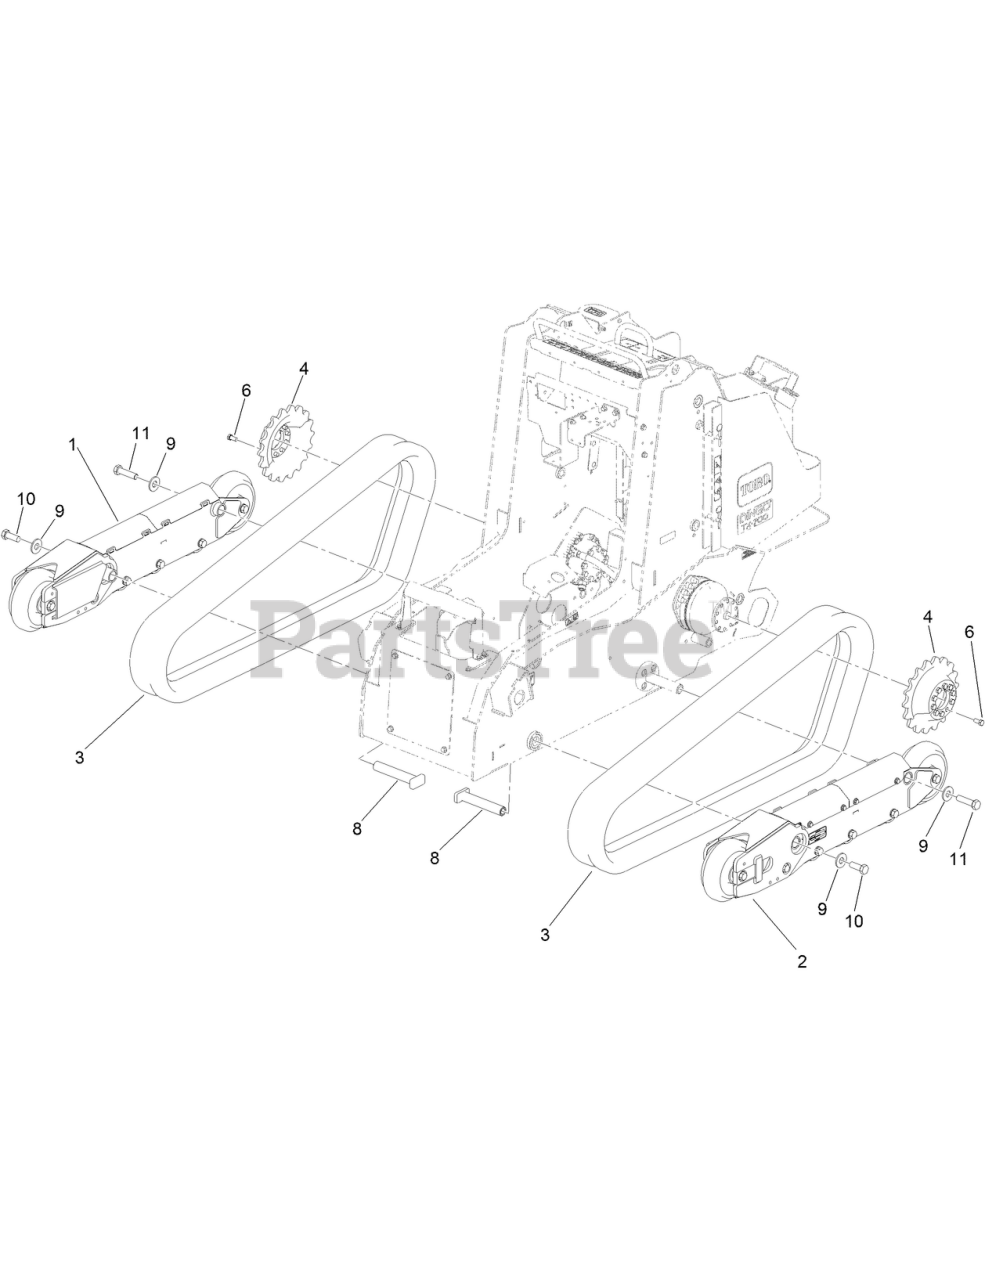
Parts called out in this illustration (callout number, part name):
1	TRACK ASM-RH
2	TRACK ASM-LH
3	TRACK-NARROW
4	SPROCKET-DRIVE, NT
6	SCREW-HH
8	PIN-TRACK
9	WASHER
11	SCREW-HH
